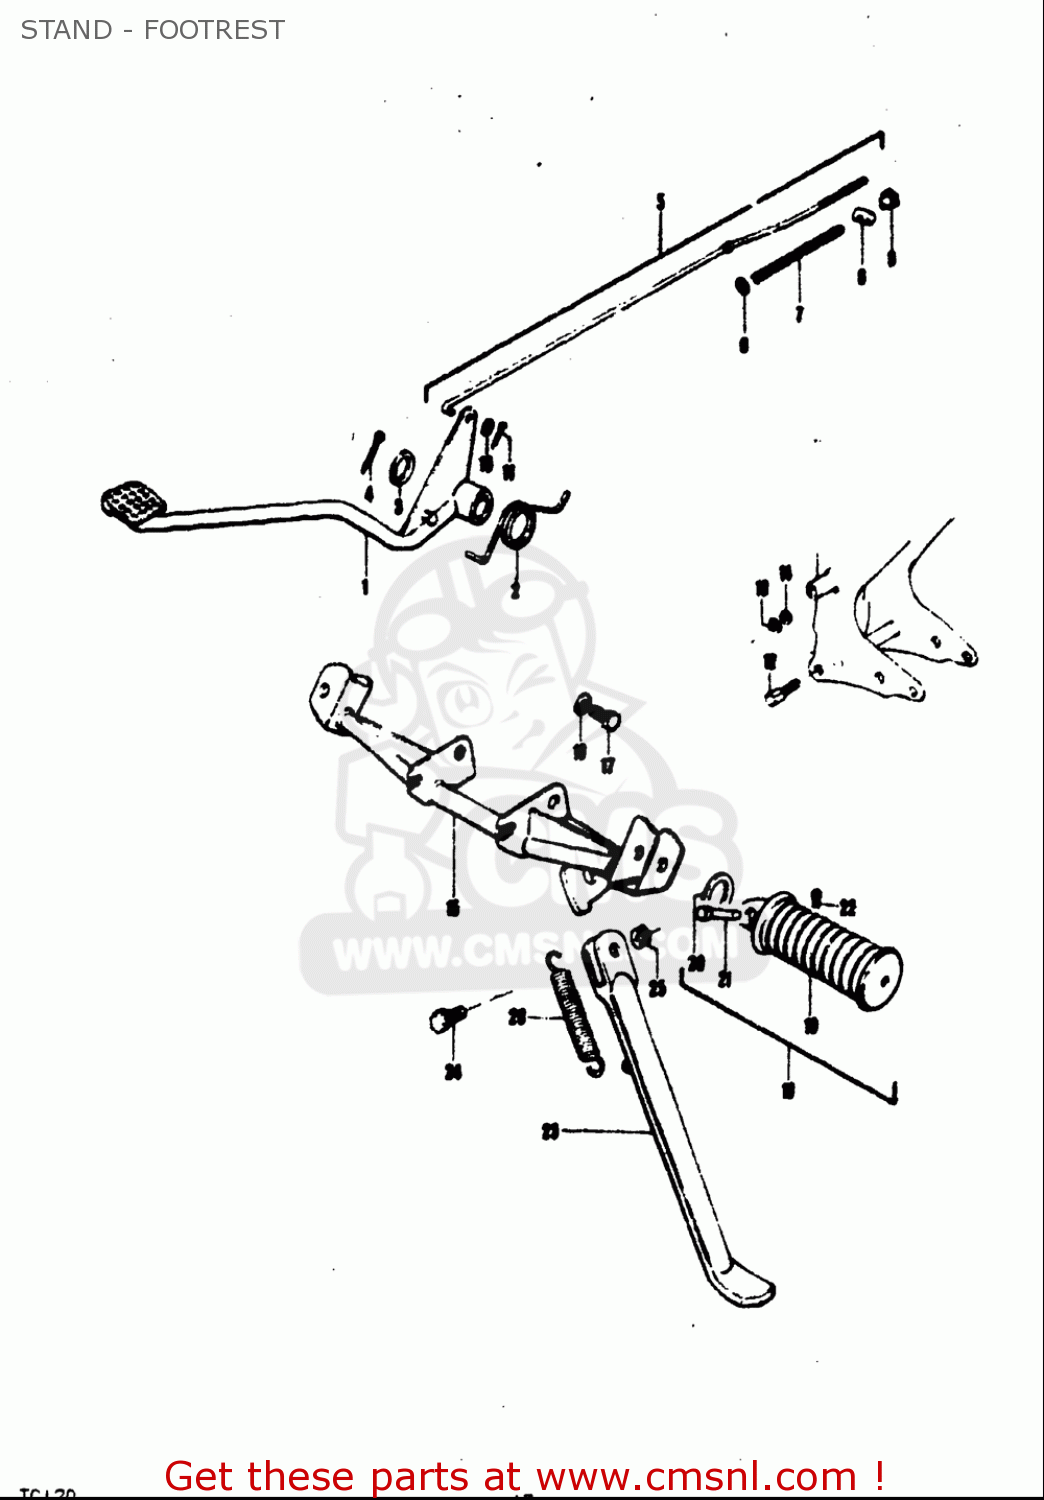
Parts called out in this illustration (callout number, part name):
2	SPRING
3	WASHER(15.5X26X2.3)
5	ROD ASSY,RR BRAKE
6	WASHER
7	SPRING
8	PIN(11X18)
9	NUT
10	WASHER
11	PIN
13	WASHER,LOCK
14	NUT
16	WASHER,LOCK
17	BOLT
20	WASHER(22.5X38X1)
21	PIN
24	BOLT(10X30)
25	NUT
26	SPRING
